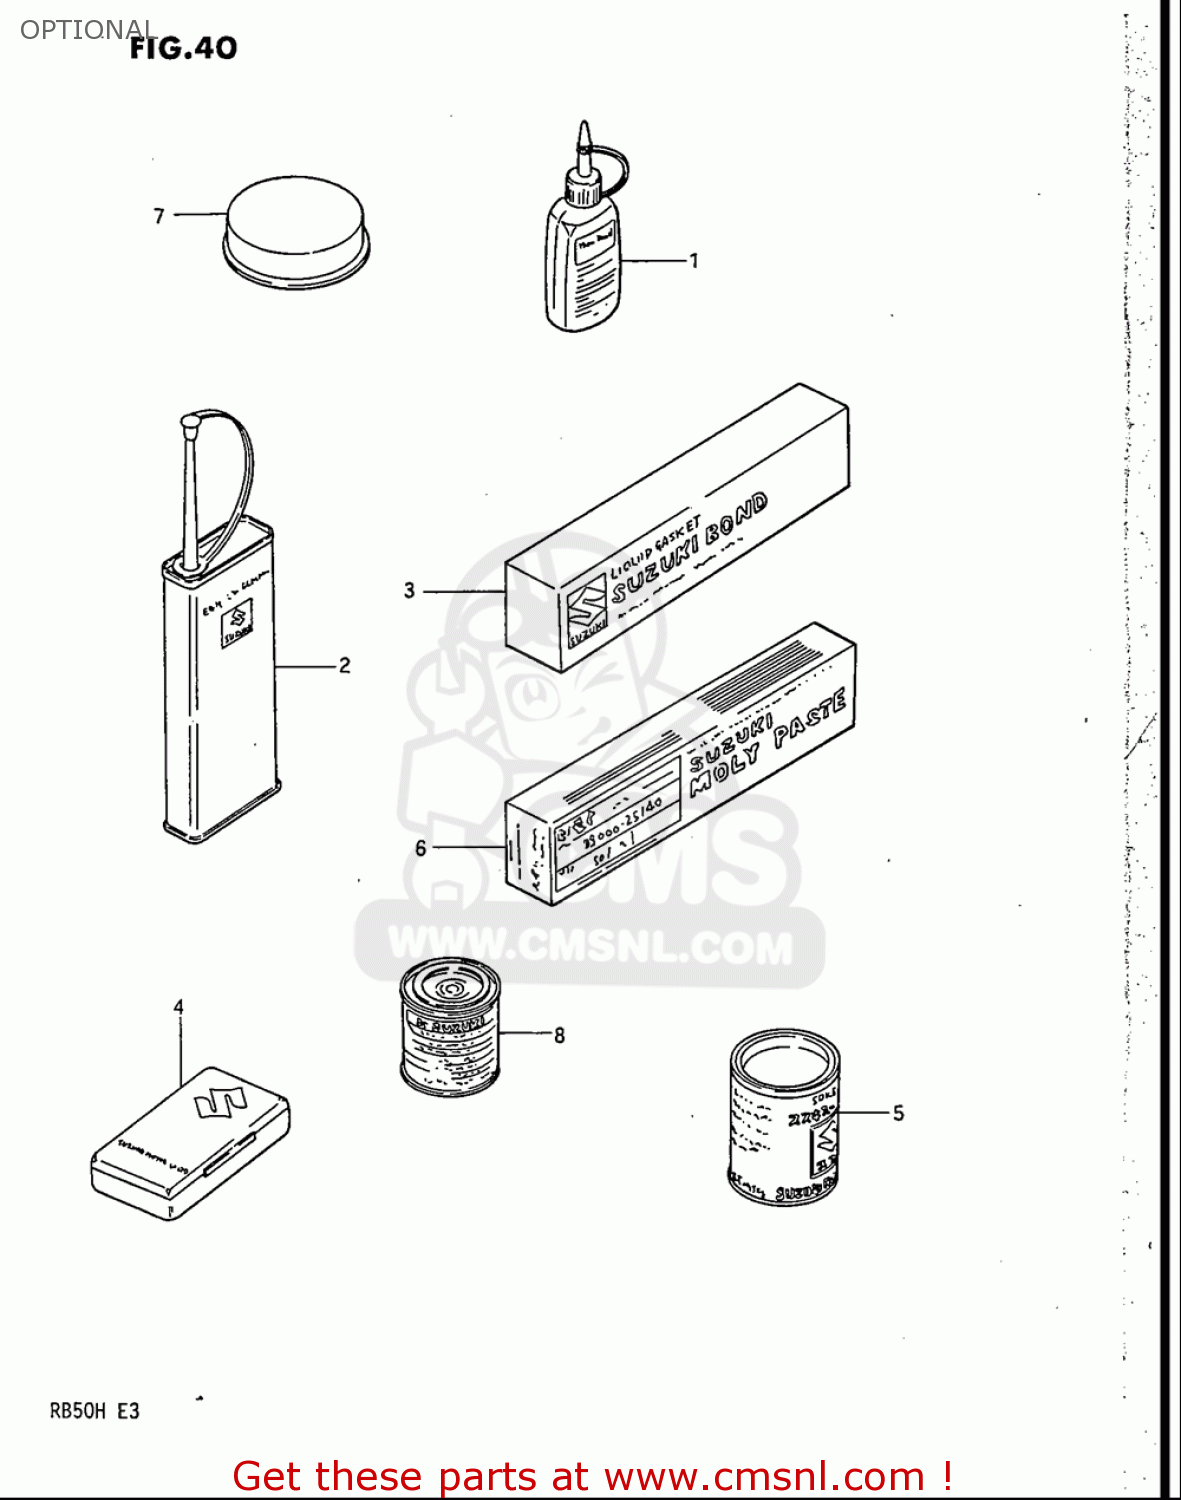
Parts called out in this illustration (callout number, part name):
1	THREAD LOCK NO.1342
2	THREAD LOCK NO.1401 CLEAR 200G
3	LIQUID GSKT NO.1207B 100G BLK
5	GREASE(C)EP2 LITHIUM 150G
6	SUZUKI MOLY PASTE
7	GREASE,PBC FOR BRK PAD 20G
